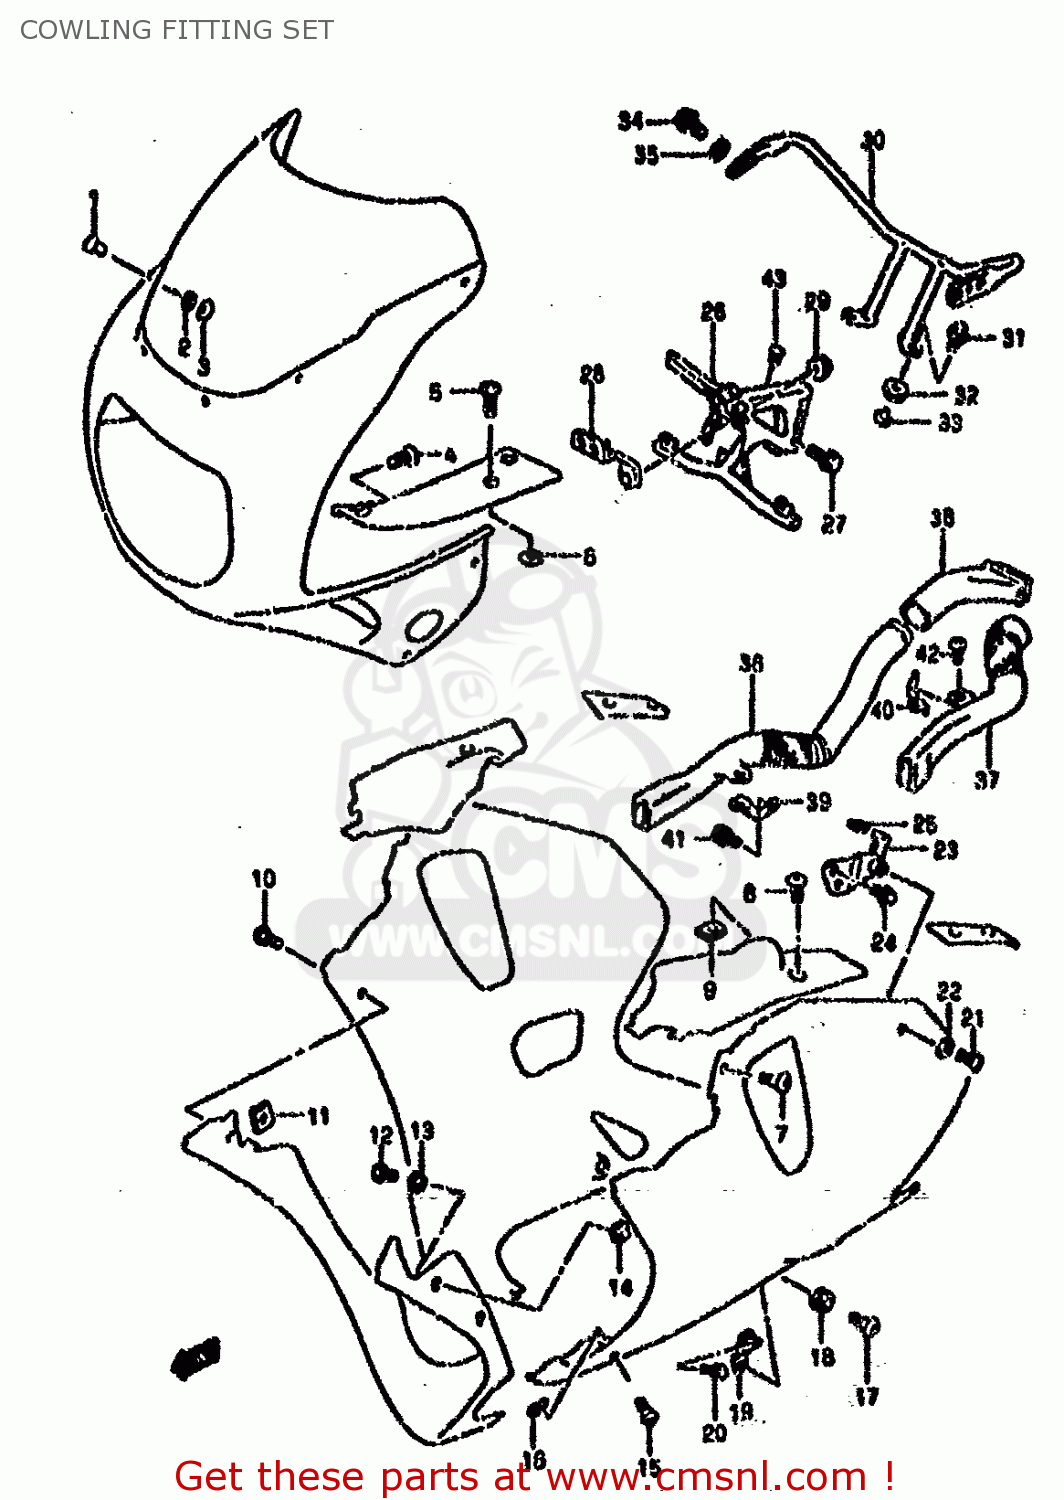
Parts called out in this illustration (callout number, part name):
1	PIN,WINDSCREEN
2	CUSHION
3	NUT
4	SCREW 5X10
5	SCREW L:12
6	NUT
7	SCREW(5X16)
8	SCREW L:12
9	NUT
10	SCREW(5X16)
11	NUT,RH & CTR UNDER COWLING
12	SCREW
13	WASHER(5.2X14X1.5)
14	NUT
15	SCREW(5X16)
16	NUT,RH & CTR UNDER COWLING
17	SCREW(6X20)
18	CUSHION
19	BRACKET,UNDER COWLING LWR,R
20	BOLT
21	SCREW(6X10)
22	WASHER
23	BRACKET,UNDER COWLING,UPPER
24	BOLT
25	NUT
26	BRACE,COWLING
27	BOLT
28	BRACKET,HEADLAMP
29	NUT
30	BRACE,RR VIEW MIRRORR
31	BOLT(6X25)
32	CUSHION
33	WASHER
34	SCREW(6X12)
35	WASHER(6.2X19X1.5)
36	PIPE,AIR INTAKE FR,R
37	PIPE,AIR INTAKE FR,L
38	PIPE,AIR INTAKE,REAR,RIGHT
39	BRACKET,AIR INTAKE,RIGHT
40	BRACKET,AIR INTAKE,LEFT
41	BOLT
42	SCREW 6X12
43	CAP(OD:14)
